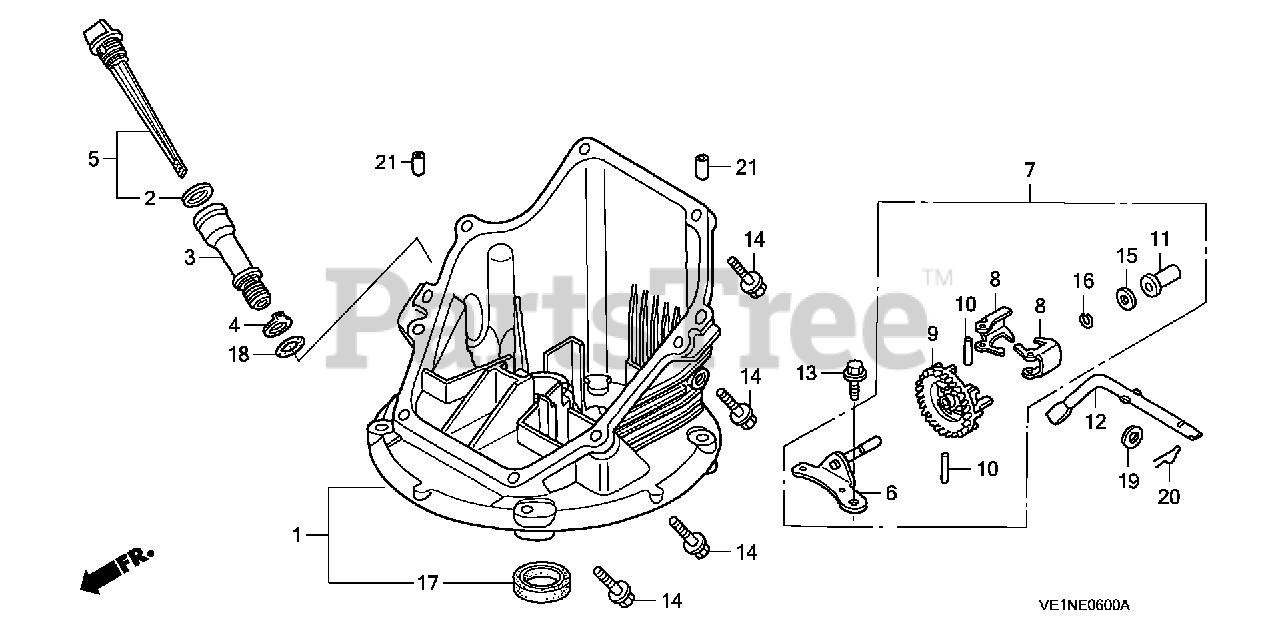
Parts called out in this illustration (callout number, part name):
1	PAN ASSY., OIL
2	GASKET, OIL FILLER CAP
3	EXTENSION, OIL FILLER
4	WASHER, EXTENSION LOCK
5	GAUGE ASSY., OIL LEVEL
6	SHAFT, GOVERNOR HOLDER
7	GOVERNOR ASSY.
8	WEIGHT, GOVERNOR
9	HOLDER, GOVERNOR WEIGHT
10	PIN, GOVERNOR WEIGHT
11	SLIDER, GOVERNOR
12	SHAFT, GOVERNOR ARM
13	BOLT, FLANGE (6X14) (CT200)
14	BOLT, FLANGE (6X25) (CT200)
15	WASHER, THRUST (6MM)
16	CLIP, GOVERNOR HOLDER
17	OIL SEAL (28X41.25X6)
18	O-RING (14.8X2.4) (NOK)
19	WASHER, PLAIN (6MM)
20	PIN, LOCK (8MM)
21	PIN, DOWEL (8X20)
